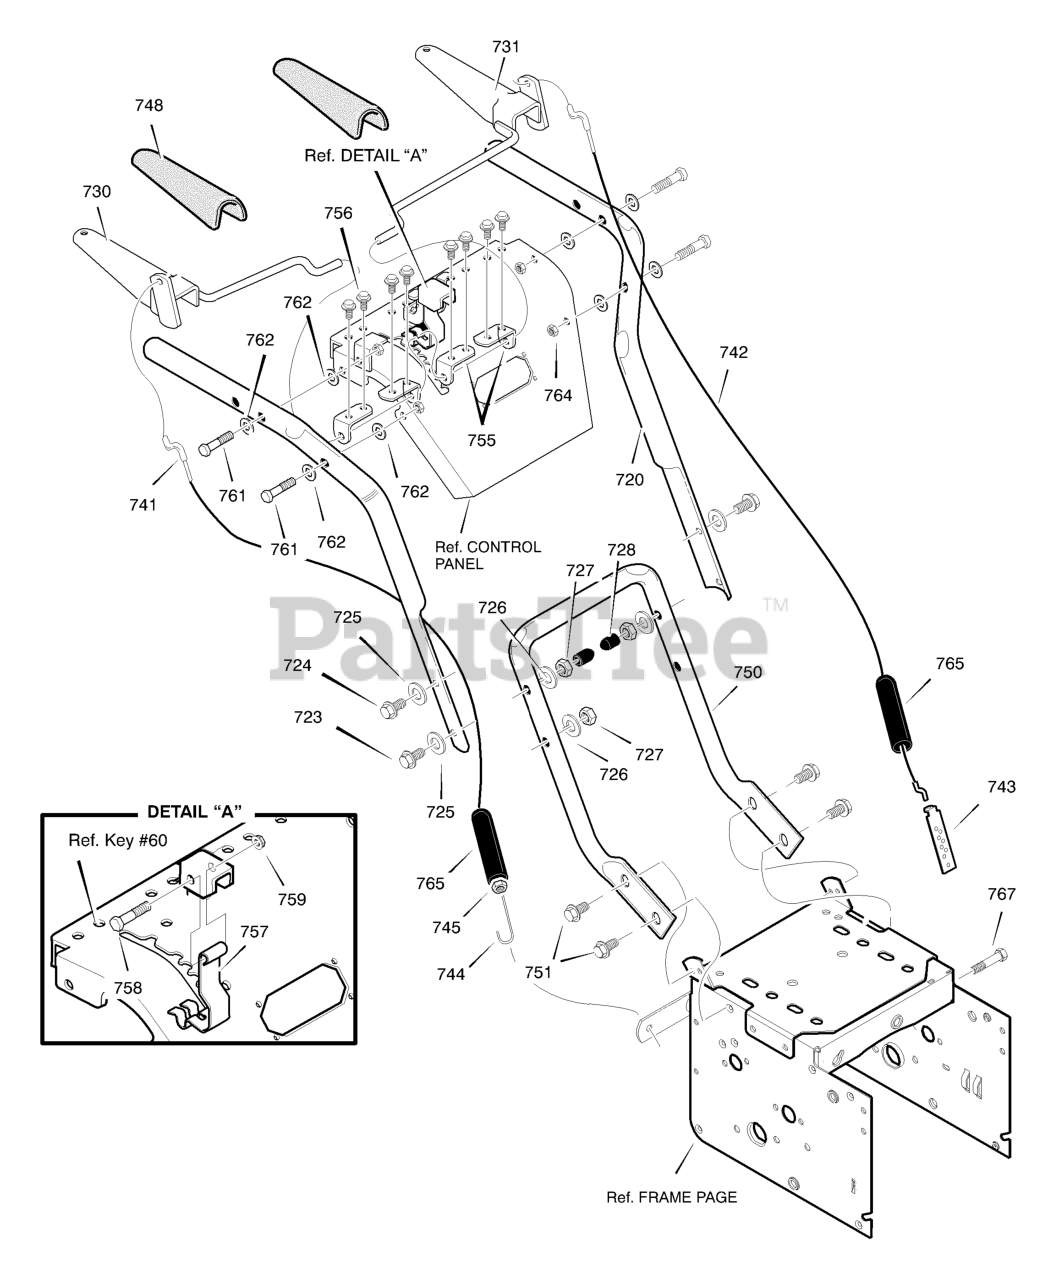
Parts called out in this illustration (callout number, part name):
720	HANDLE, UPPER LH
721	HANDLE, UPPER RH
723	SCREW
724	SCREW
725	WASHER, FLAT
726	WASHER, SPTLK
727	NUT, REGHEX
728	STOP, PLASTIC
730	LEVER, ASSY CLUTCH DRIVE RH
731	LEVER, ASSY CLUTCH DRIVE LH
741	CABLE, AUGER CLUTCH
742	CABLE, AUGER DRIVE
743	BRACKET, CABLE ADJUSTER
744	SPRING, AUGER CLUTCH
745	NUT, 1/4-20
748	GRIP, CLUTCH HANDLE
750	HANDLE, LOWER
751	SCREW
754	SCREW
755	BRKT, ROD
756	SCREW
757	SPRING, CAM LOCK
758	BOLT, HEX
759	NUT
761	SCREW
762	WASHER, FLAT
764	NUT, HEXFLNG
765	BOOT, CLUTCH SPRING
767	BOLT, HEX 1/4-20 X 1.50
